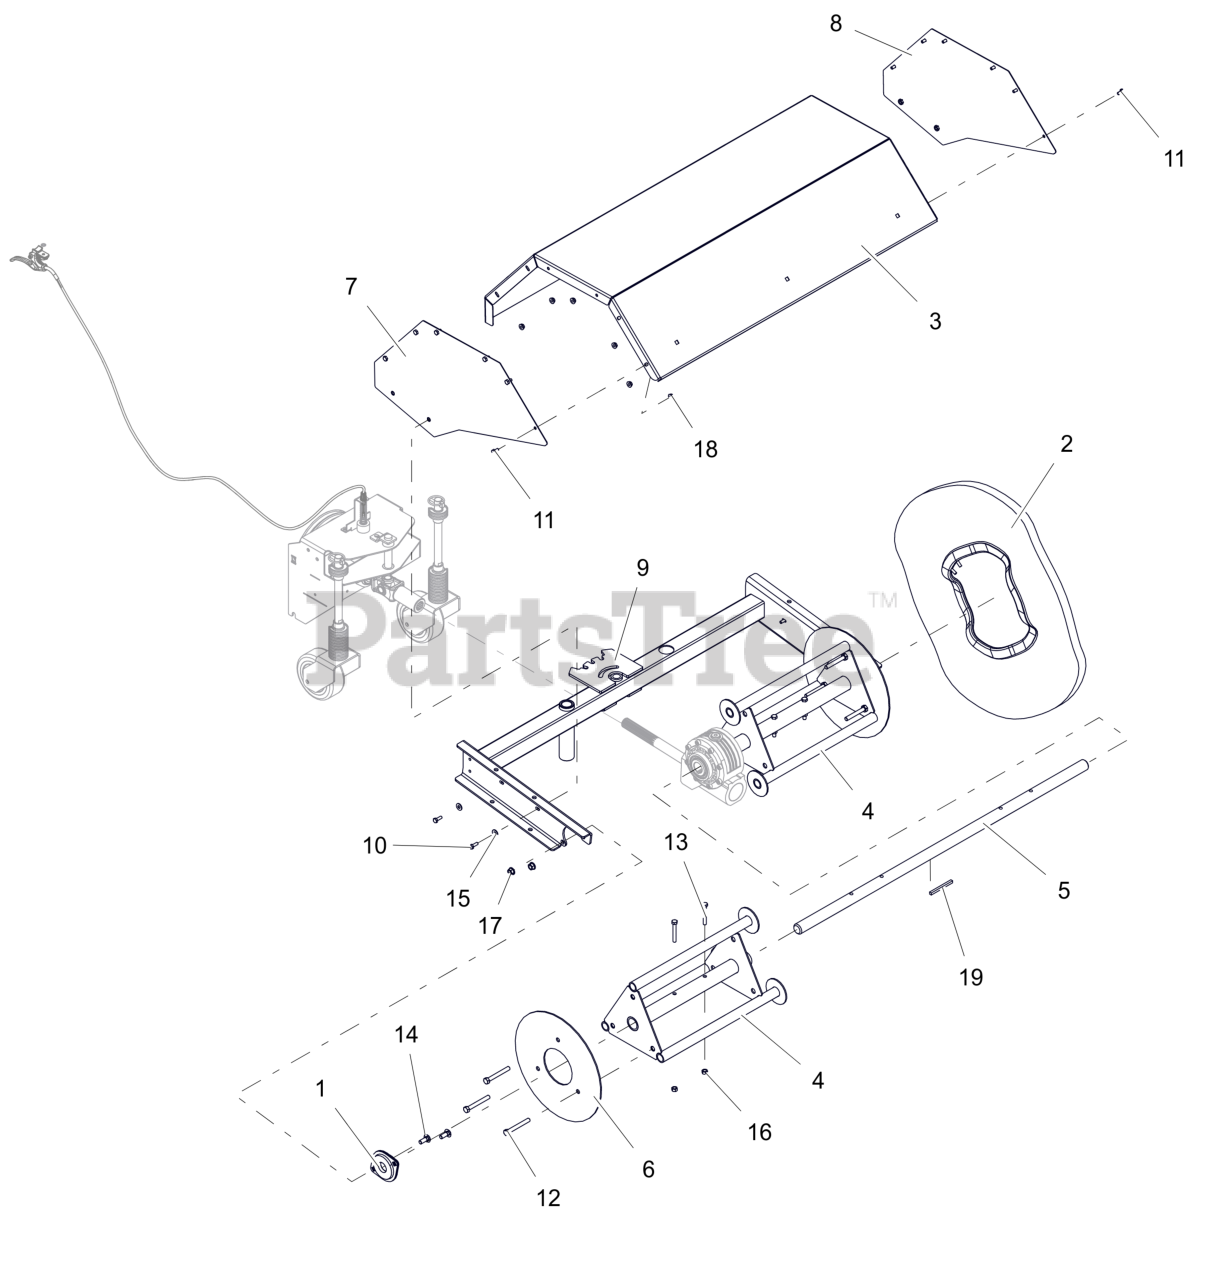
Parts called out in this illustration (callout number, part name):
1	BEARING,2 BOLT FLANGE 1-1/8 ID
2	KIT, BRISTLE - SET OF 18
3	COVER, TOP - 36 PB W/DECAL
4	PB36 DRIVE CORE SERVICE KIT
5	CENTER, SHAFT
6	PLATE, END RETAINER
7	WLDT, SIDE COVER - RH
8	WLDT, SIDE COVER - LH
9	FRAME, POWER BROOM 36"
10	BLT, HEX .25-20X.75 G5 ZCC
11	BLT,HEX .25-20X.50 G5 ZCC
12	BLT, HEX .38-16X3.00F G5 ZCC
13	BLT, HEX .31-18X2.25 G5 ZCC
14	BLT, RHSN .38-16X1.00 G5 ZCC
15	WSHR, FLT .312X.734X.065 ZCC
16	NUT,LK-CTR .31-18 GA ZCC
17	NUT-LK-TOP-FLG .38-16 ZC120
18	NUT-LK-TOP-FLG .250-20 GF ZCC
19	KEY .25 X .25 X 3IN
